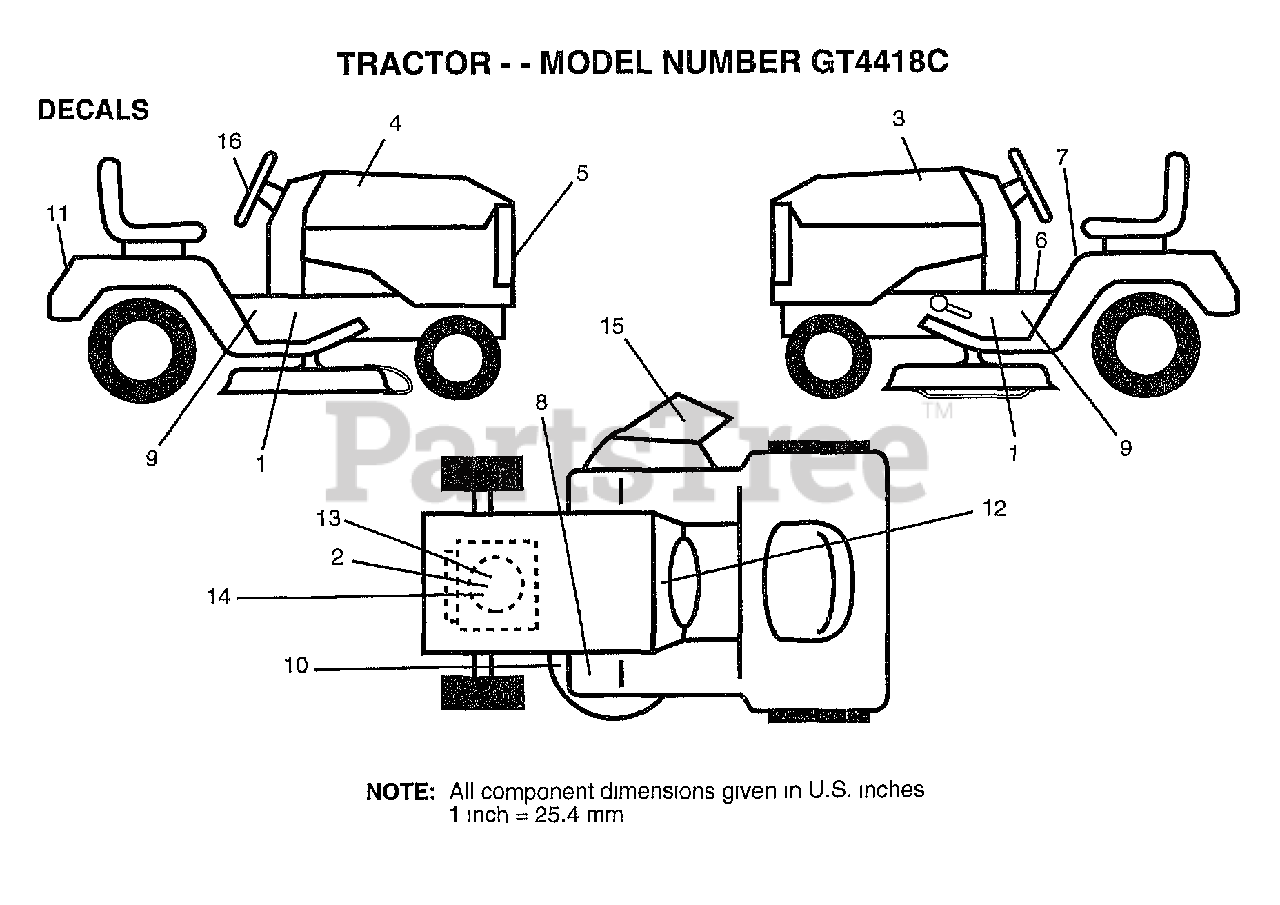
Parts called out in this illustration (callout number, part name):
1	DECAL CHASSIS
2	DECAL B&S 18 HP OPLLN/IC
3	DECAL HD LH
4	DECAL HD RH
5	DECAL LOGO GRILLE
6	DECAL BRAK PARK
7	DECAL CAUT FEND
8	DECAL CLUT/BRAKE
9	DECAL CHASSIS YT
10	"DECAL.V.BELT.44"""
11	DECAL.FEN.GT.KMAR
12	DECAL INST OP DAS
13	DECAL ENG B/S REWIND
14	DECAL ENGINE B/S INST
15	DECAL DANGER CT/F
16	DECAL.INST.WHL.ST
